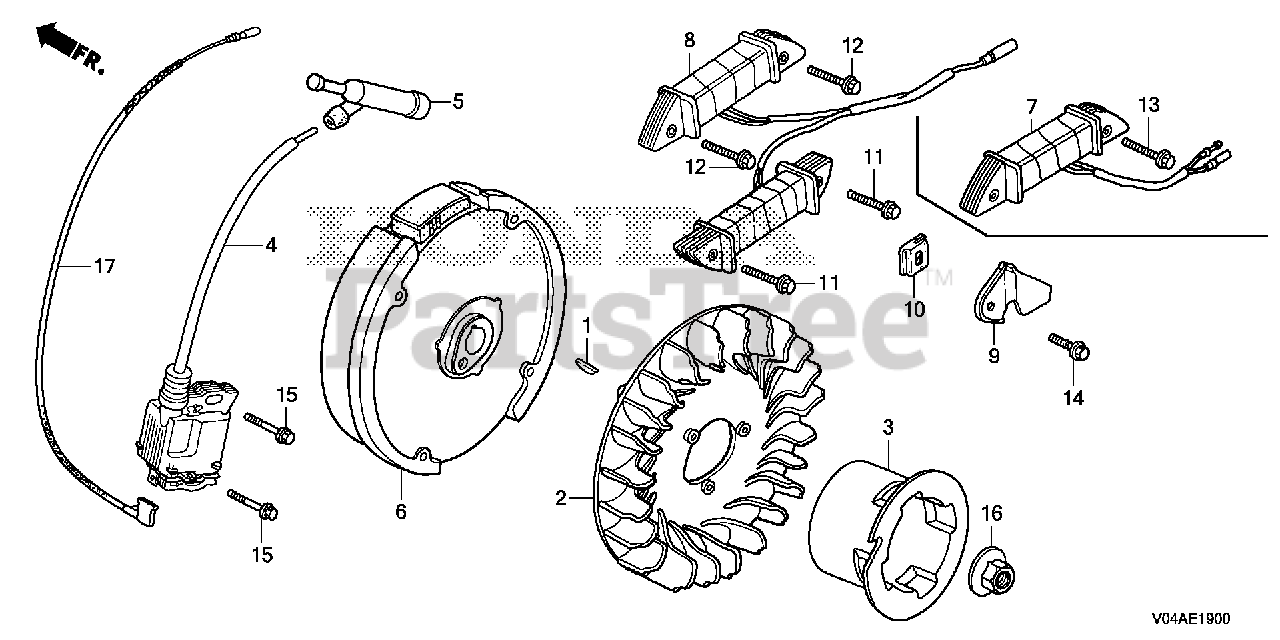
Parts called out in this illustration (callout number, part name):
1	KEY, SPECIAL WOODRUFF (25X18)
2	FAN, COOLING
3	PULLEY, STARTER
4	COIL ASSY., IGNITION (TEC)
5	CAP ASSY., NOISE SUPPRESSOR (NGK)
5	CAP ASSY., NOISE SUPPRESSOR (TEC)
6	FLYWHEEL (LAMP)
8	COIL ASSY., LAMP (12V/50W)
9	CLAMP, WIRE
10	GROMMET, WIRE
11	BOLT, FLANGE (6X28) (CT200)
12	BOLT, FLANGE (6X28) (CT200)
14	BOLT, FLANGE (5X10) (CT200)
15	BOLT, FLANGE (6X25) (CT200)
16	NUT, SPECIAL (14MM)
17	WIRE, STOP SWITCH (370MM)
